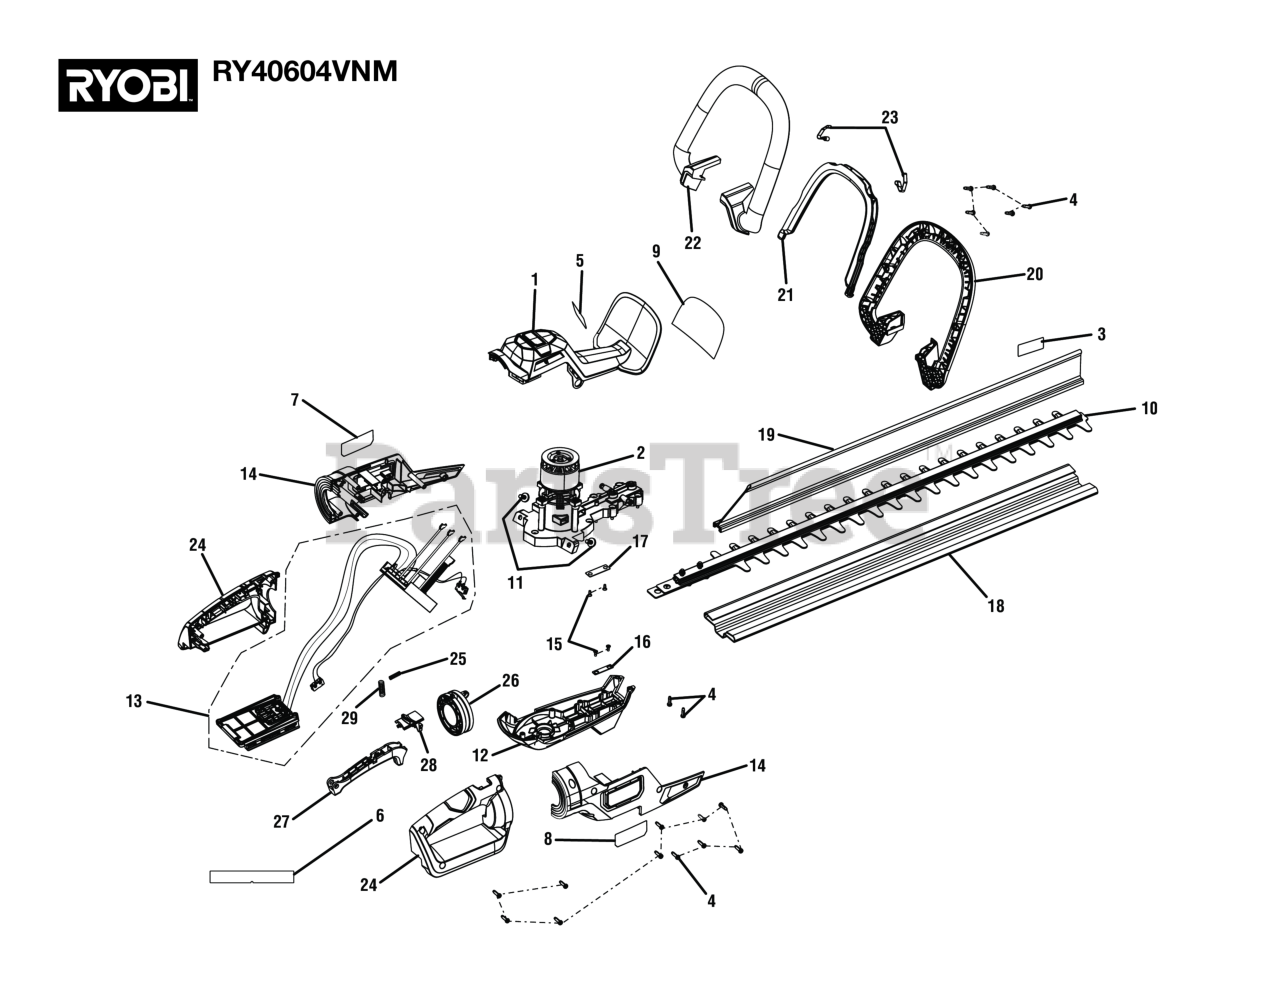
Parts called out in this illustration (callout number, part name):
1	Top Cover Assembly (Inc. Key Nos. 5 & 9)
2	Motor and Gear Box Assembly
3	Warning Label
4	Screw (M4 x 14 mm, T15 Torx Pan Hd.))
5	40V HP Brushless Label
6	Rotating Handle Label
7	40V HP Logo Label
8	Data Label
9	Icons Warning Label
10	Blade Assembly
11	Screw (M5 x 13 mm, Pan Hd.)
12	Bottom Housing
13	Battery Foot and Switches Assembly
14	Motor Housing Assembly (Inc. Key Nos. 6-8)
15	Screw (M3 x 8 mm, Flat Hd.)
16	Flat Washer
17	Flat Washer
19	Hedge Sweep Assembly (Inc. Key No. 3)
20	Assist Handle Front Half
21	Assist Handle Safety Trigger
22	Assist Handle Rear Half
23	Spring Plate
24	Rear Handle Assembly
25	Lock-Off Button Spring
28	Lock-out Slider
29	Trigger Spring
